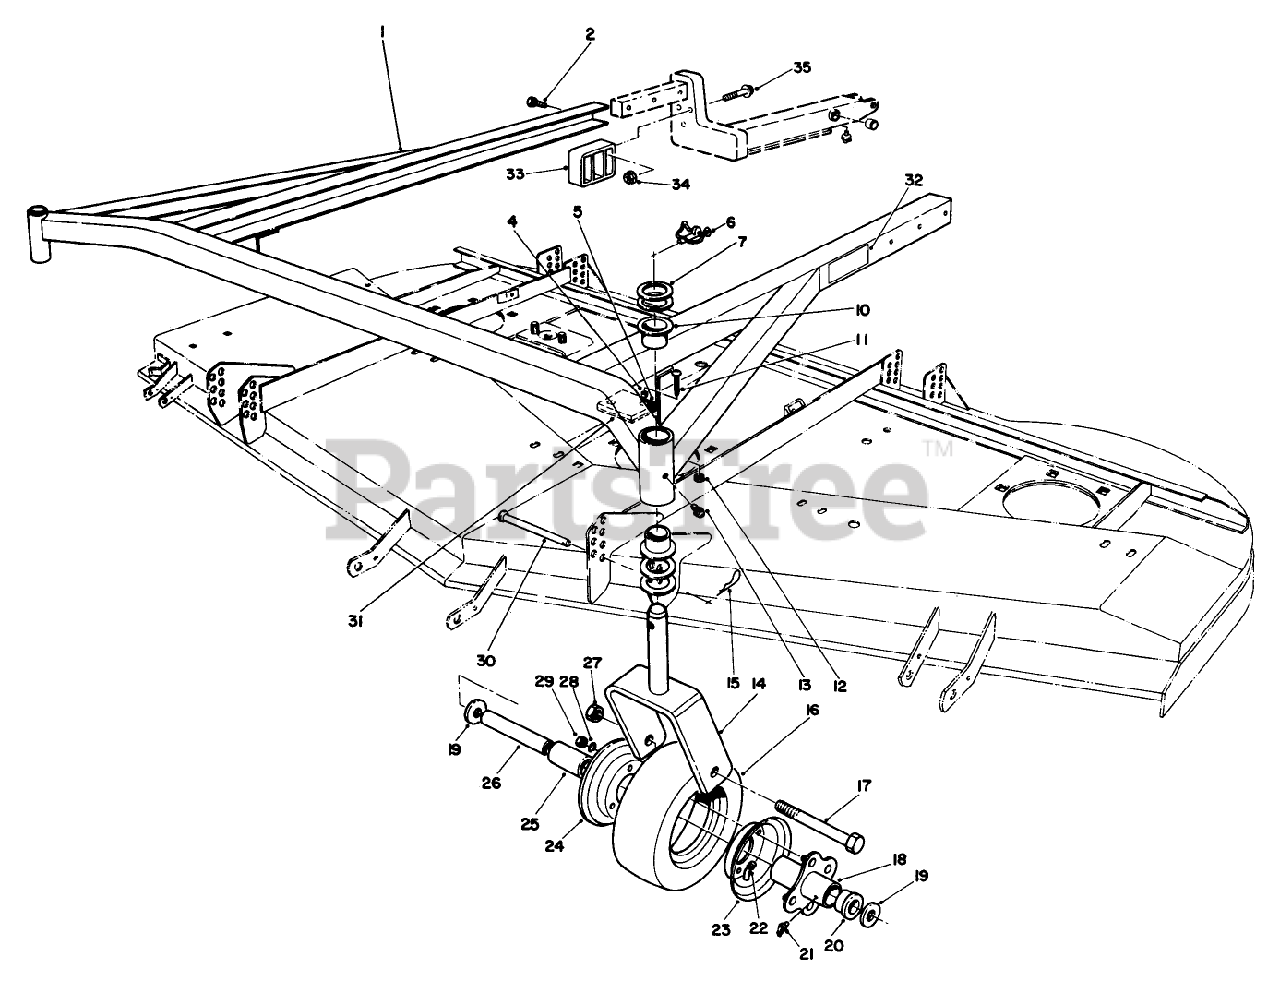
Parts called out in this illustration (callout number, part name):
1	Carrier Frame Assembly (Incl. Ref. #10)
2	SCREW-HH
4	SPACER
5	CUSHION-RUBBER
6	PIN-LYNCH
7	WASHER-THRUST
10	Bushing
12	NUT-LOCK, NI
13	FITTING-GREASE
14	Castor Fork
15	PIN-HAIR
17	SCREW-HH
18	HUB-CENTER
19	WASHER-FLAT
20	BEARING-OUTSIDE
21	FITTING-GREASE
22	TUBE-INNER (W/VALVE)
23	FEMALE WHEEL HALF
24	MALE WHEEL HALF
25	BEARING-ROLLER
26	SPANNER-TIRE
27	NUT-HEX
28	WASHER-LOCK
29	NUT-HEX
30	PIN-CLEVIS
31	SHIM-CUSHION
32	DECAL-HOC, LH
33	Cradle-Rear
34	NUT-FLANGE
35	SCREW-HHF
